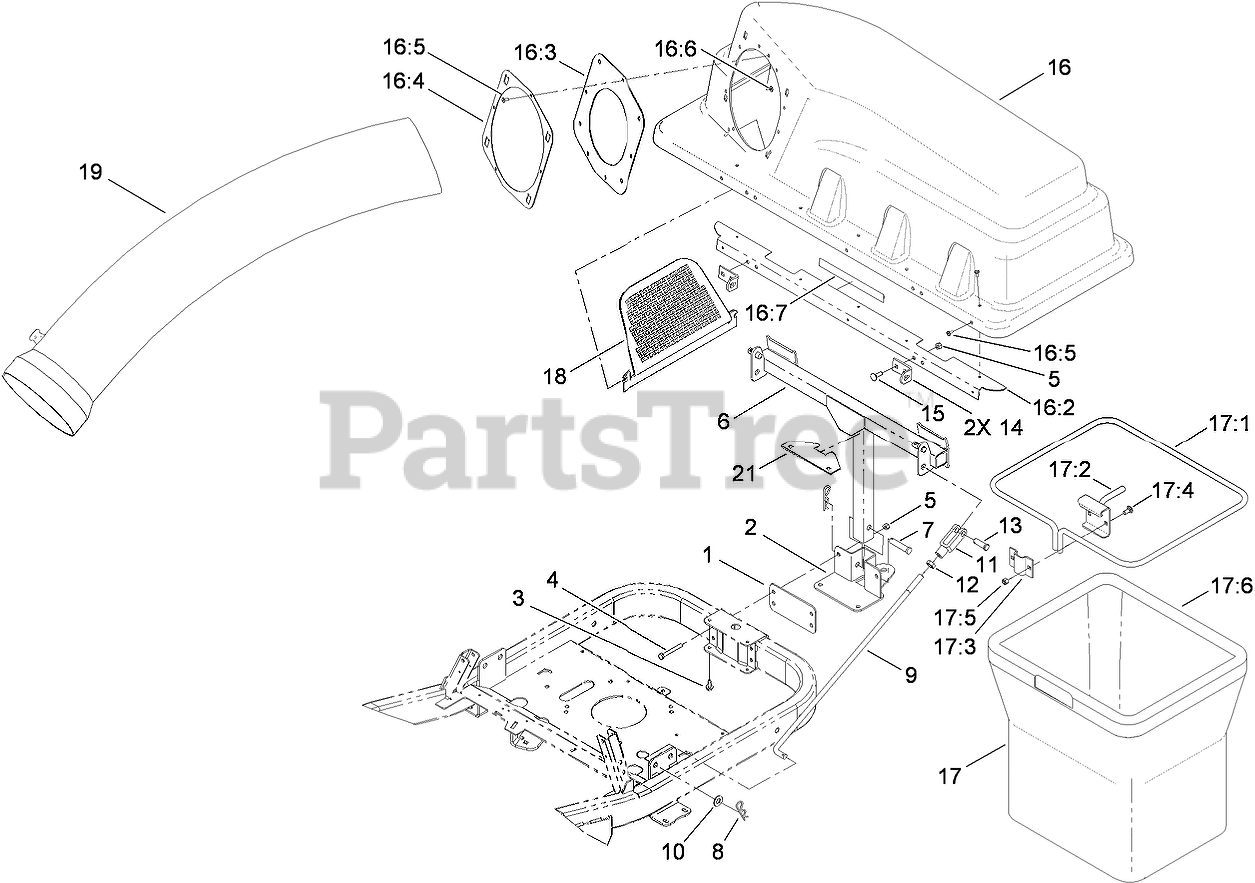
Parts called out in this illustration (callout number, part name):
2	SUPPORT-BAGGER
3	SCREW-HWHTF
4	SCREW-HH
5	NUT-LOCK, NI
6	FRAME-PIVOT
7	PIN-CLEVIS
8	PIN-HAIR
9	ROD-BAGGER
10	WASHER-FLAT
11	CLEVIS
12	NUT-JAM
13	PIN-CLEVIS
14	BRACKET-PIVOT, HOPPER
15	BOLT-CARR
16	BAGGER TOP ASM
16:2	STIFFENER-TOP, BAG
16:3	GASKET
16:4	RING-RETAINER
16:5	RIVET-BLIND
16:6	WASHER-FLAT
16:7	DECAL-CAUTION, BAGGER
17	BAG ASM
17:1	FRAME-BAG
17:2	HANGER ASM
17:4	BOLT-CARR
17:5	NUT-LOCK, NI
18	SCREEN-BAGGER
19	TUBE-BAGGER
21	PLATE-SPACER
